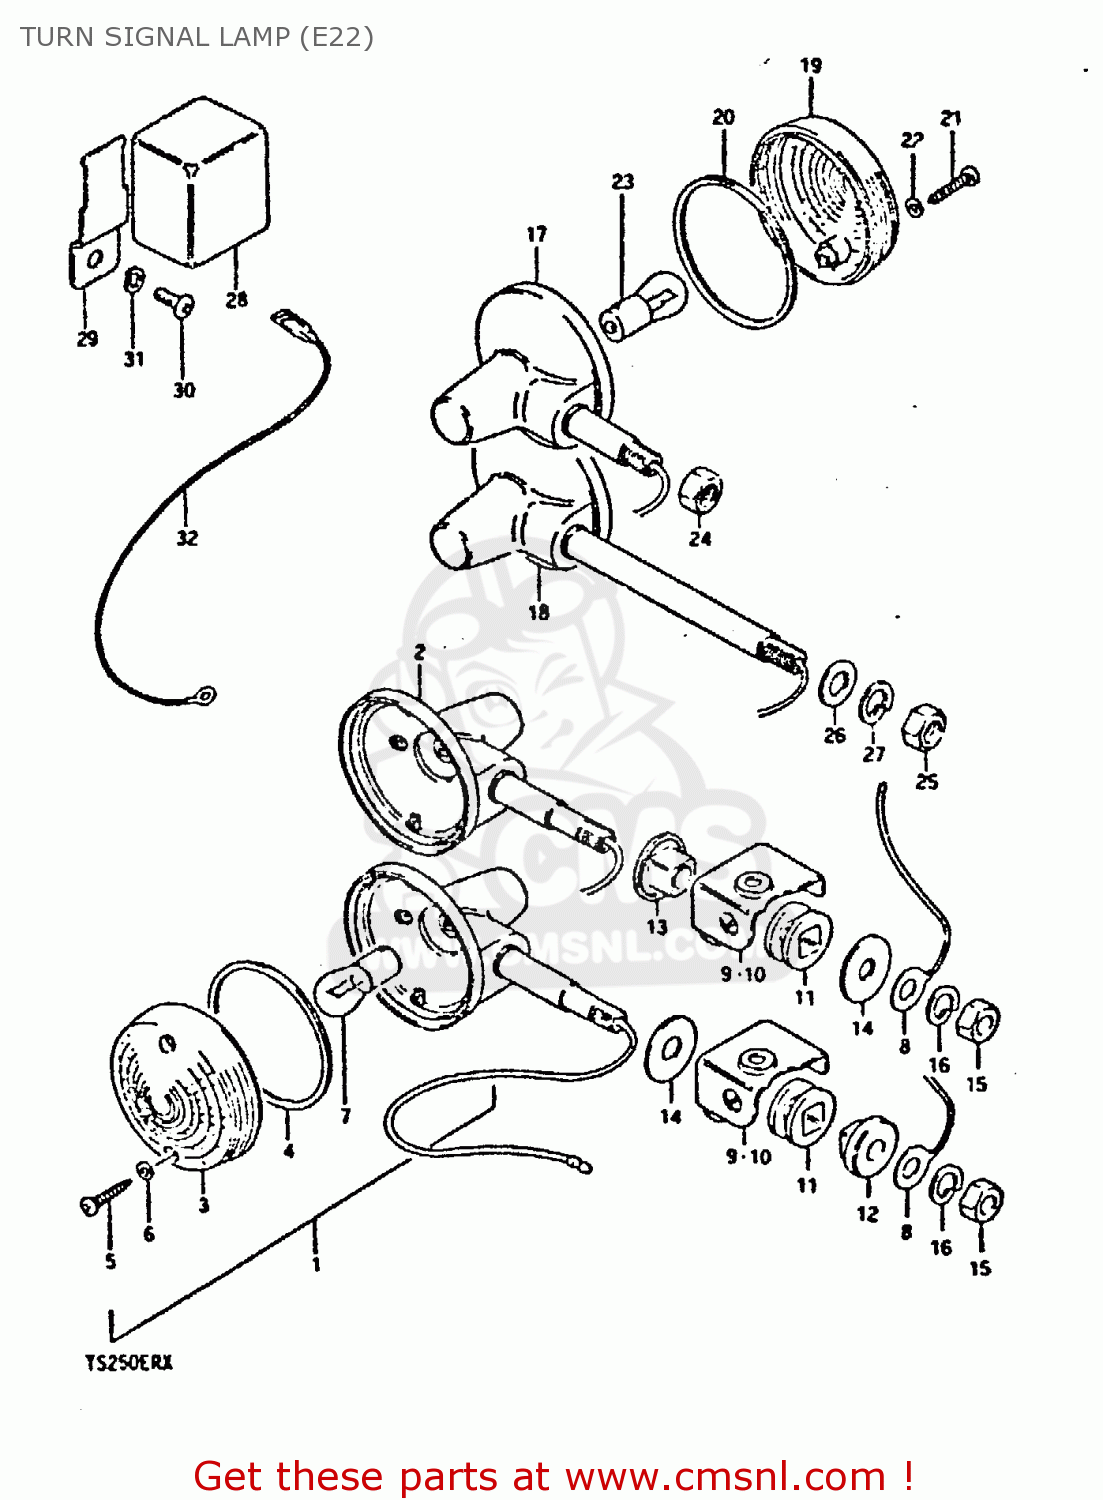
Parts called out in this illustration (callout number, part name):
1	LAMP, FRONT TURN SIGNAL
2	LAMP ASSY,FR TURN SIGNAL
3	LENS
4	GASKET (NAS)
5	SCREW
6	GASKET (NAS)
7	BULB (6V,21W)
8	LEAD WIRE,EARTH
9	BRACKET,TURNSIGNAL LAMP,R
10	BRACKET,TURNSIGNAL LAMP,L
11	CUSHION
12	SPACER,RR TURNSIGNAL LAMP
13	SPACER
14	WASHER (10.5X30X2.3)
15	NUT
16	LOCK WASHER
17	LAMP, REAR TURN SIGNAL
18	LAMP, REAR TURN SIGNAL
19	LENS
20	GASKET (NAS)
21	SCREW
22	GASKET (NAS)
23	BULB (6V,21W)
24	NUT
25	NUT
26	WASHER
27	LOCK WASHER
28	RELAY, TURN SIGNAL
29	BRACKET,TURN SIGNAL RELAY
30	SCREW 6X12
31	LOCK WASHER
32	LEAD WIRE, RELAY EARTH
